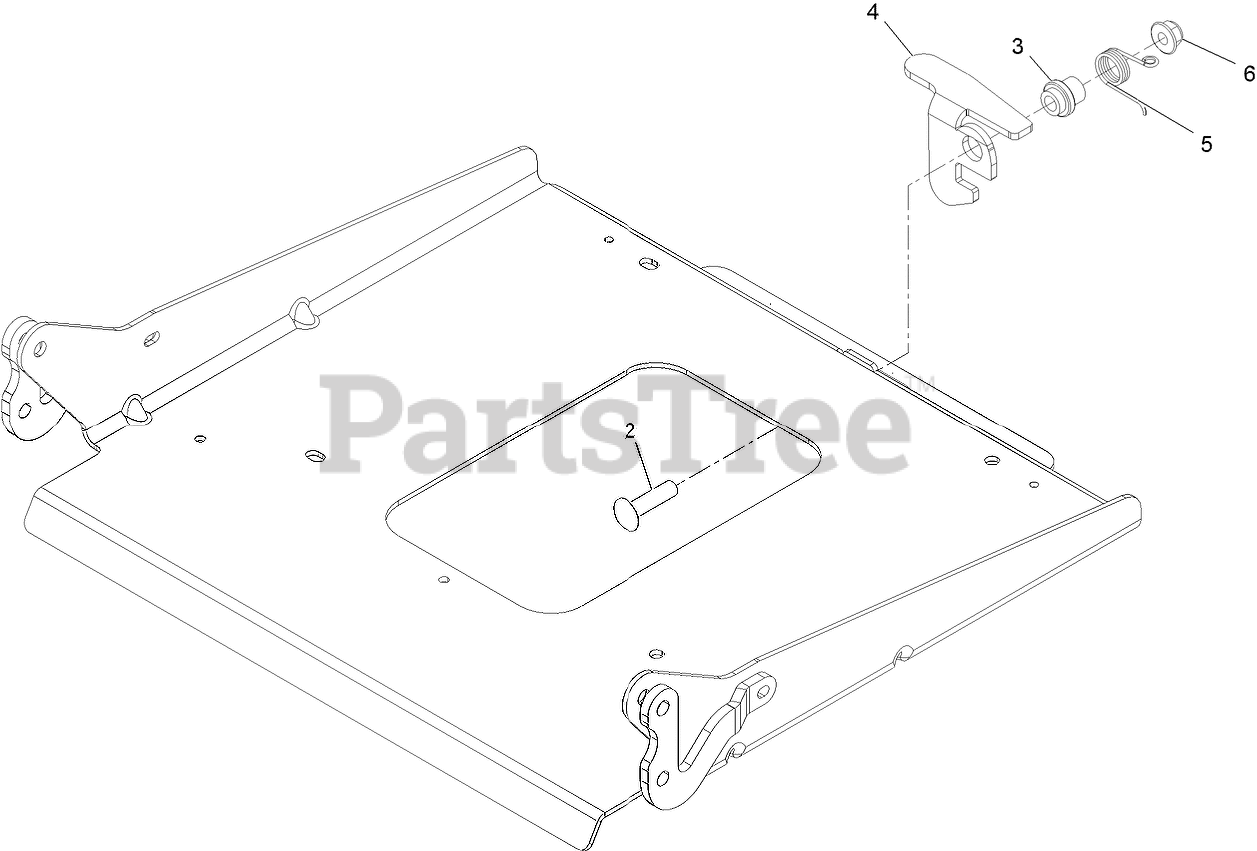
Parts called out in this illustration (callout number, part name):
2	SCREW-CARR
3	BUSHING-LATCH, SEAT
4	LATCH-CATCH, SINGLE
5	SPRING-TORSION, LATCH
6	NUT-HF, NI
